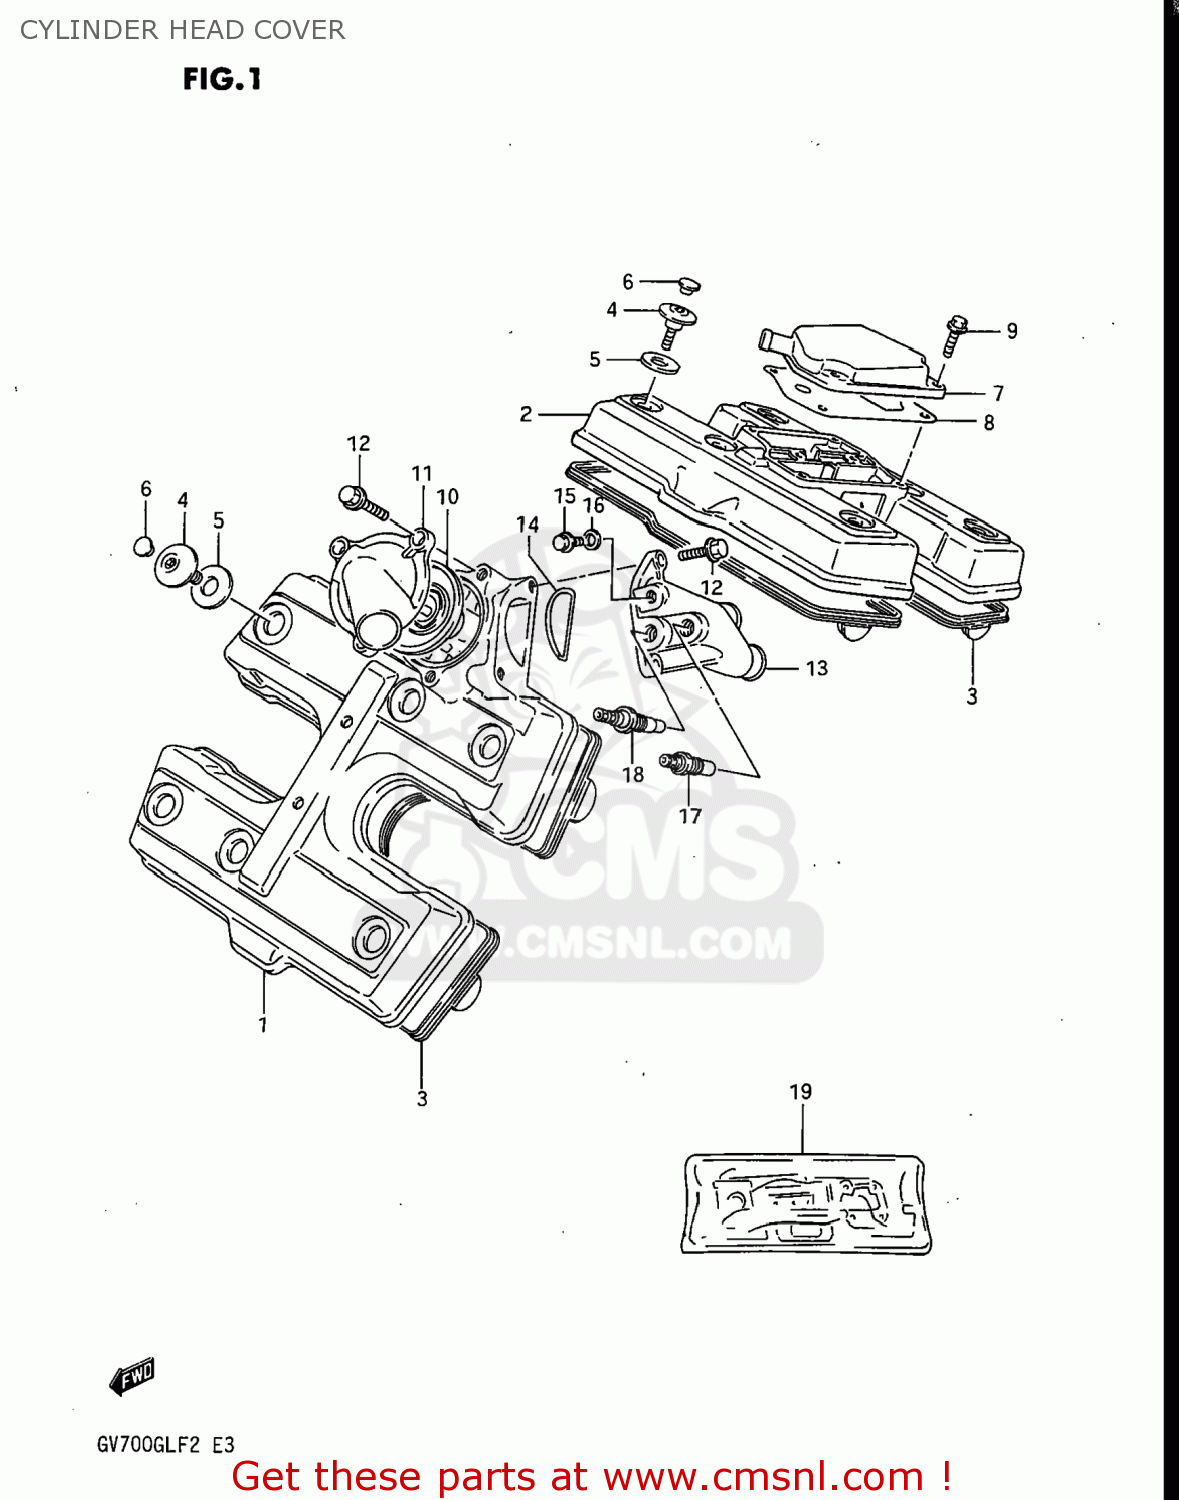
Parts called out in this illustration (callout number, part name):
1	COVER,CYLINDER HEAD
2	COVER,CYLINDER HEAD
3	GASKET,CYLINDER HEAD COVER (NAS)
4	BOLT(7X5.5)
5	WASHER
6	CAP(OD:10)
7	COVER,BREATHER
8	GASKET (NAS)
9	BOLT,REAR
10	THERMOSTAT,WATER
11	COVER,THERMOSTAT
12	BOLT
13	CONNECTOR,THERMOSTAT,INLET
14	O-RING,THERMO CONNECTOR
15	UNION
16	GASKET(6.2X11X1).2 (NAS)
17	SWITCH,RADIATOR FAN
18	GAUGE ASSY,WATER TEMP
19	GASKET SET
